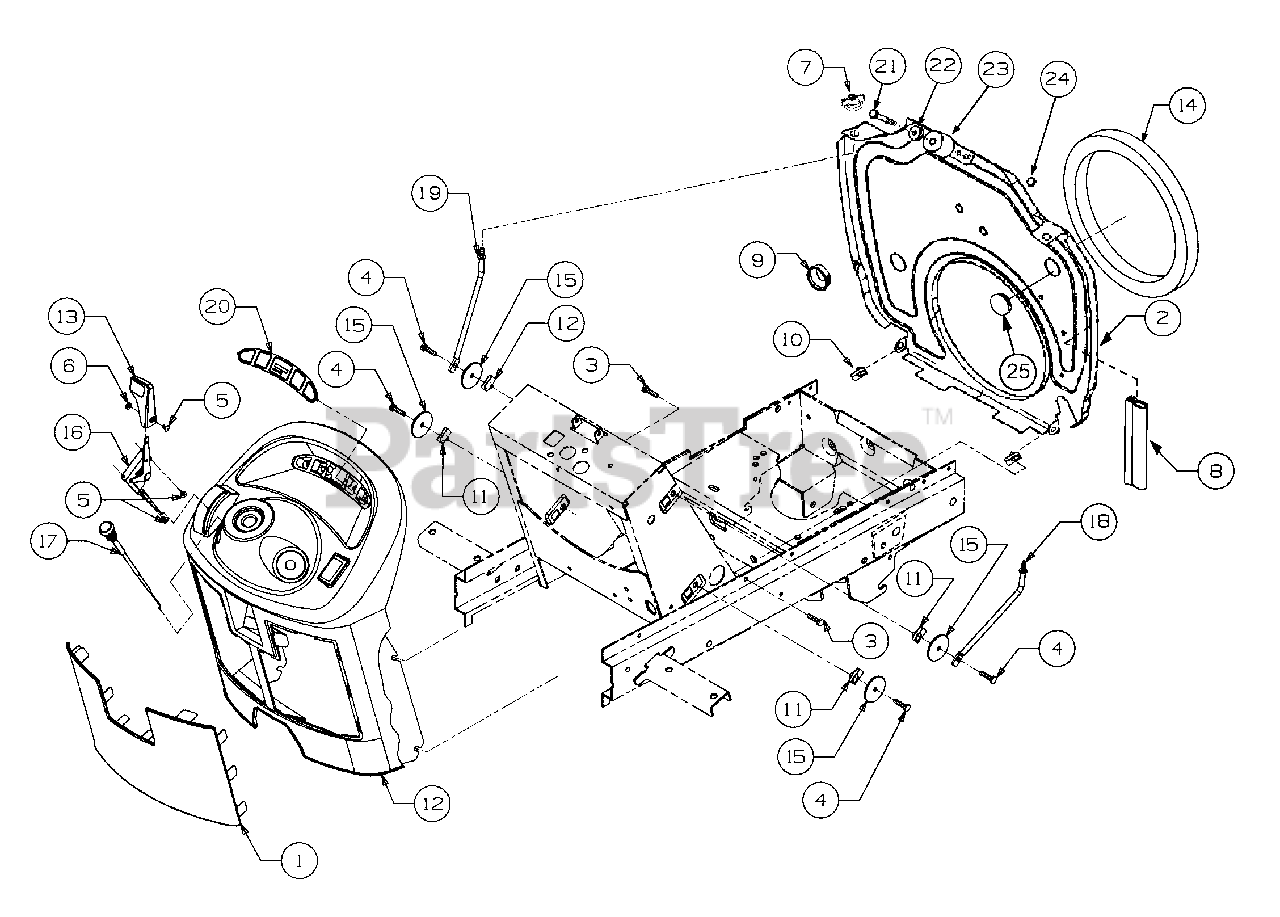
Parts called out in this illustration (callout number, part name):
4	Screw, Hex Cap, 1/4-20 x 1.0
5	Screw, Cross Rec Trus, #8-32 x .38
6	Nut, #8-32
7	Nut, Wing w/Bell Washer 1/4-20
8	Seal, Push On Trim
9	Bushing, Snap, 7/8 ID
10	Nut, U-Type Speed, 1/4-20
11	Nut, U-Clip, 1/4-20
12	Panel, Dash
13	Knob, Throttle
14	Seal Ring, Foam
15	Washer, Flat, .285 x 1.75 x .10
16	Control, Throttle
17	Control, Choke
18	Rod, RH Mounting
19	Rod, LH Mounting
20	Label, Dash
21	Screw, Hex Cap,1/4-20 x 1.75 GR5
22	Washer, Flat, .283 x .75 x .030
23	Roller, Hood Latch
24	Nut, Hex Sems, 1/4-20
25	Plug. Button
